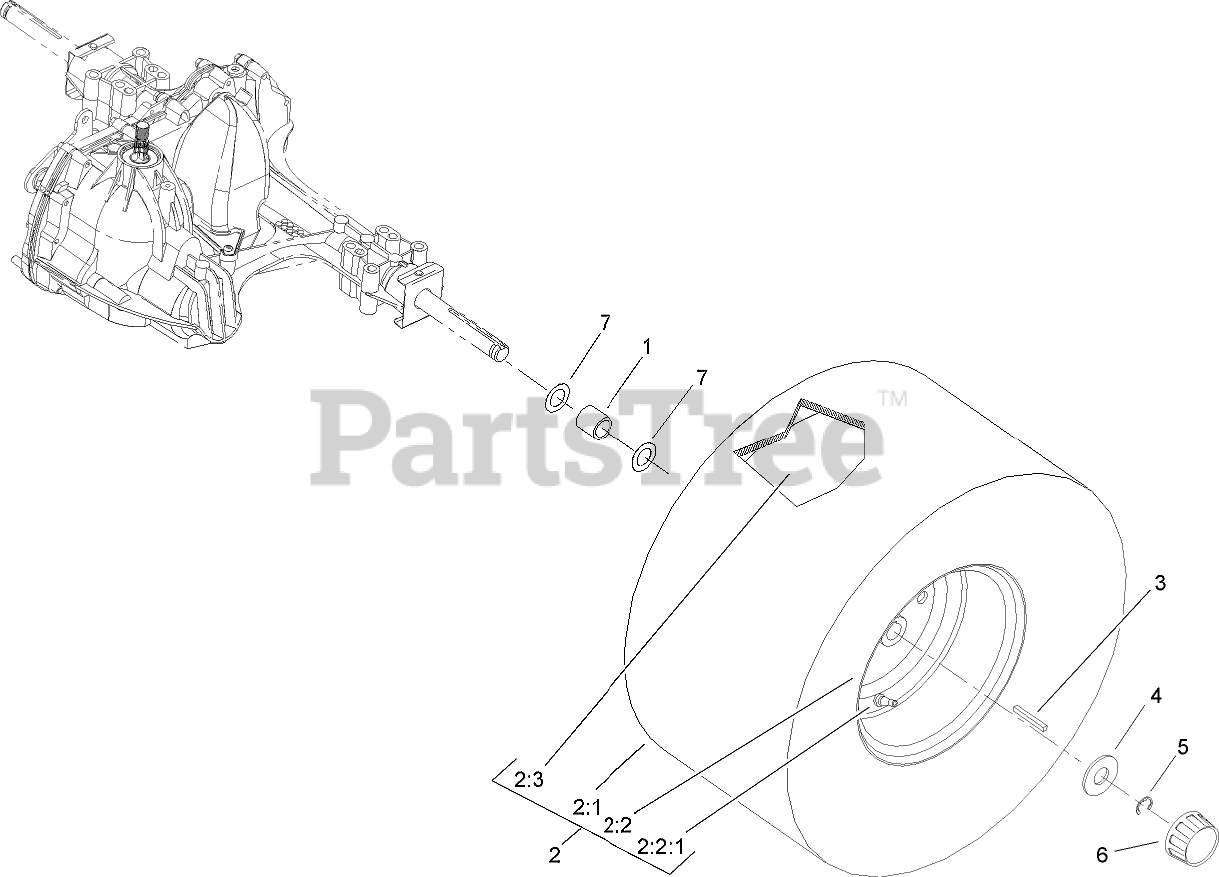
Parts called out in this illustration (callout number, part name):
1	SPACER-WHEEL
2	REAR WHEEL & TIRE ASM
2:2:1	STEM-VALVE
2:3	TUBE-INNER
3	KEY-SQUARE
4	WASHER-PLAIN
5	E-RING
6	CAP-HUB
7	WASHER-THRUST
